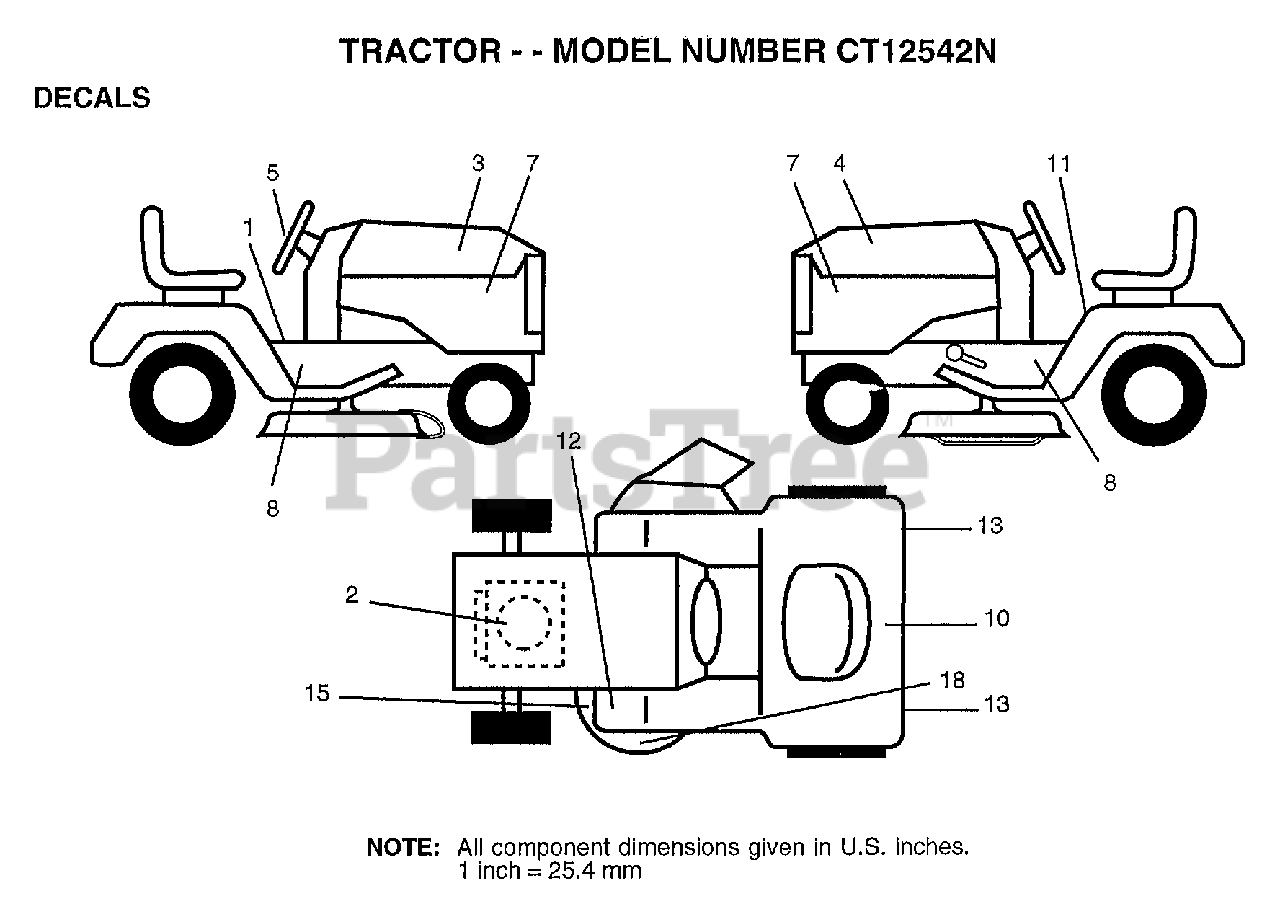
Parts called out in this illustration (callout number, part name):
1	"DECAL DASH,OPER."
2	DECAL, HP ENGINE
3	DECAL HOOD RH
4	"DECAL HOOD,LH"
5	DECAL INST STG WH
7	"DECAL PANEL,SIDE"
8	"DECAL CHASSIS 42"""
10	DECAL.BATRY.3-3908
11	"DECAL DANGER,FEND"
13	REFLECTOR-TAIL YT
15	"DECAL-SCHEM,BELT"
